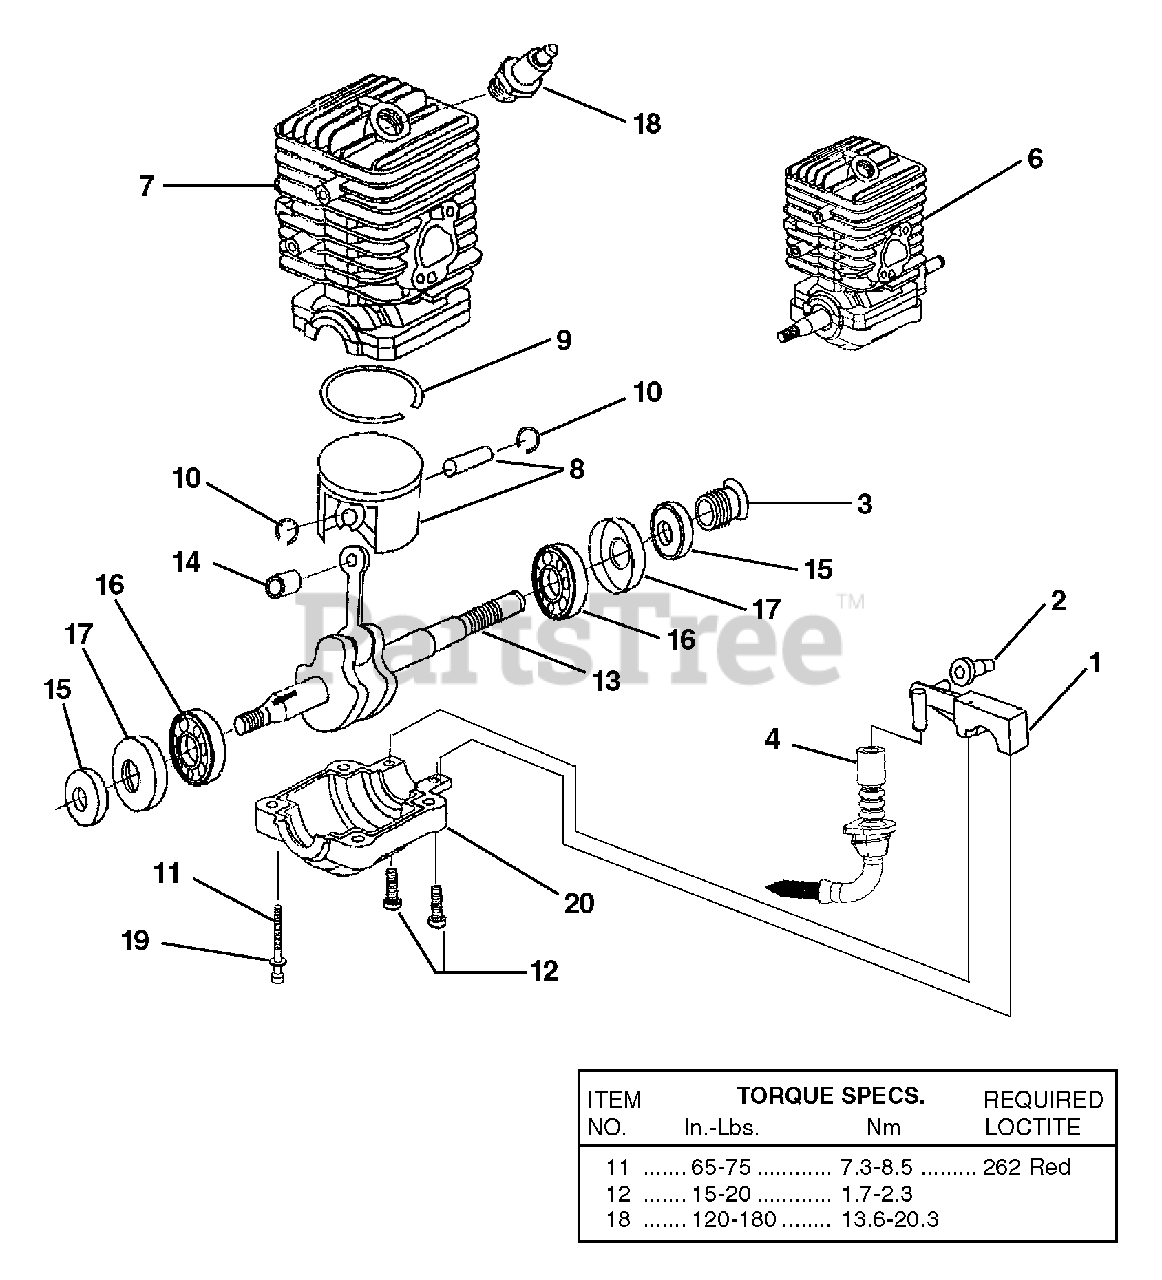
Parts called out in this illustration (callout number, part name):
1	Oil Pump Kit
2	Grommet,Oil Outlet
3	Left Hand Worm
4	Oil Intake Tube w/Filter
6	Short Block,Complete (33cc)
7	Cylinder Kit (33cc)
8	Piston & Pin (33cc)
9	Piston Ring
10	Ring, Retaining
11	Screw, Cap-Socket Hd.(10-24x2")
12	Screw, Pan Hd.,(8-32x5/8")
13	Crankshaft & Rod Assembly
14	Bearing, Needle
15	Shaft Seal
16	Bearing & Rubber Case
17	Rubber Case
18	Spark Plug
19	Washer
20	Lower Crankcase
